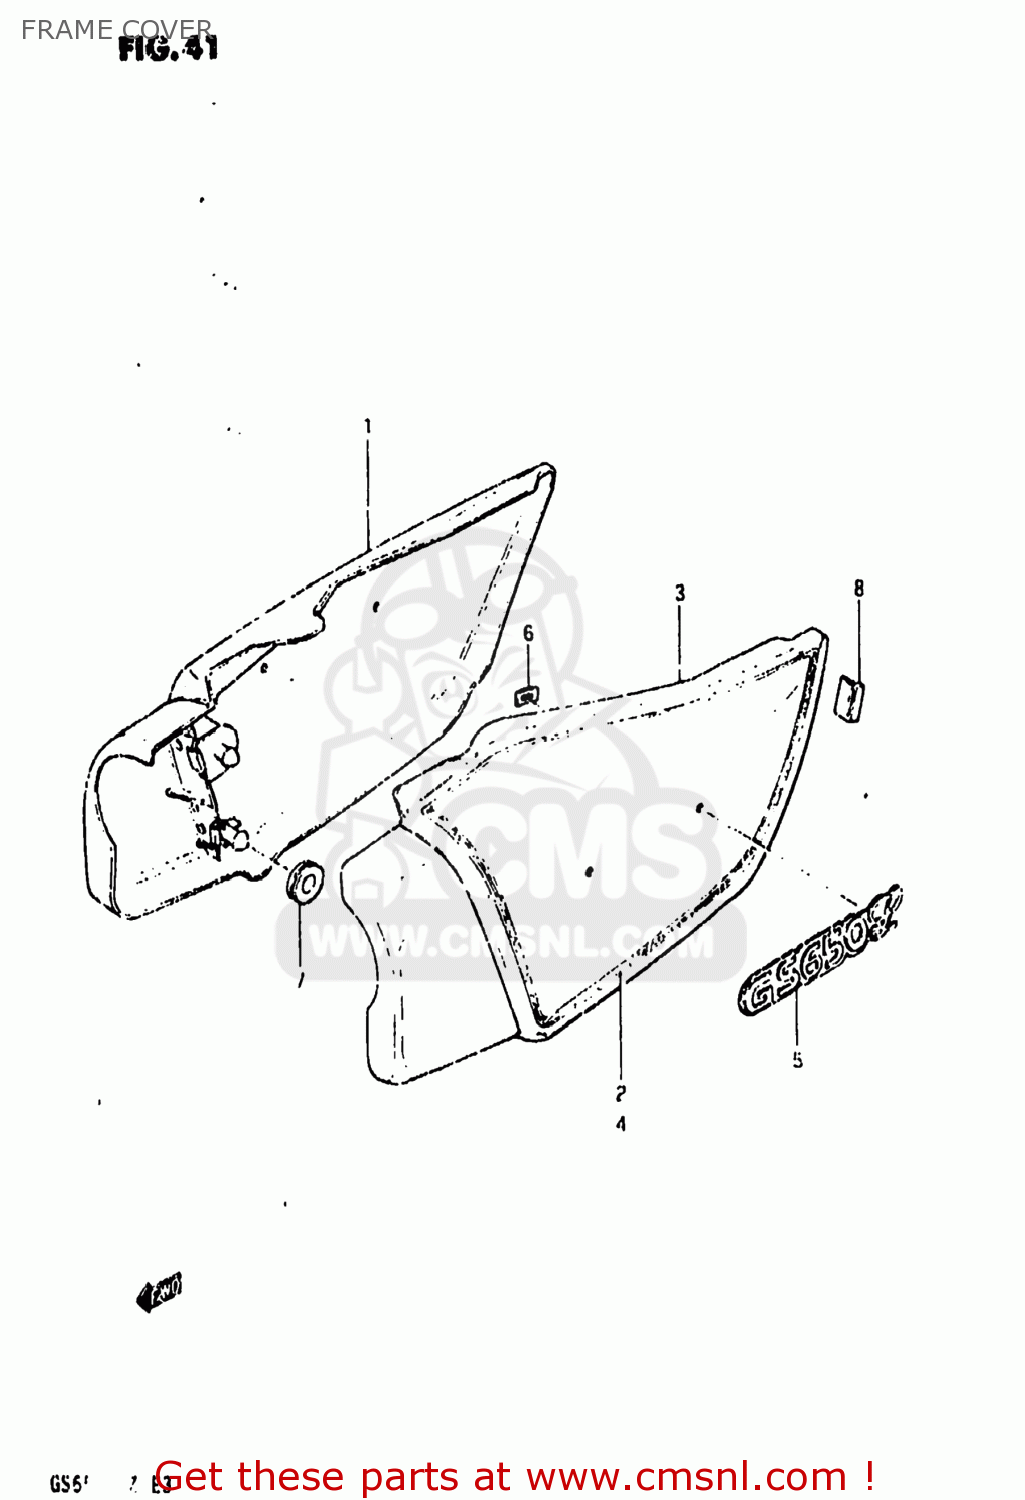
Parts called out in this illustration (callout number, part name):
1	COVER ASSEMBLY,FRAME,RIGHT
2	TAPE SET,FRAME COVER
3	COVER ASSEMBLY,FRAME,LEFT
4	TAPE SET,FRAME COVER
5	EMBLEM
6	NUT
7	CUSHION
8	CUSHION,FRAME COVER
